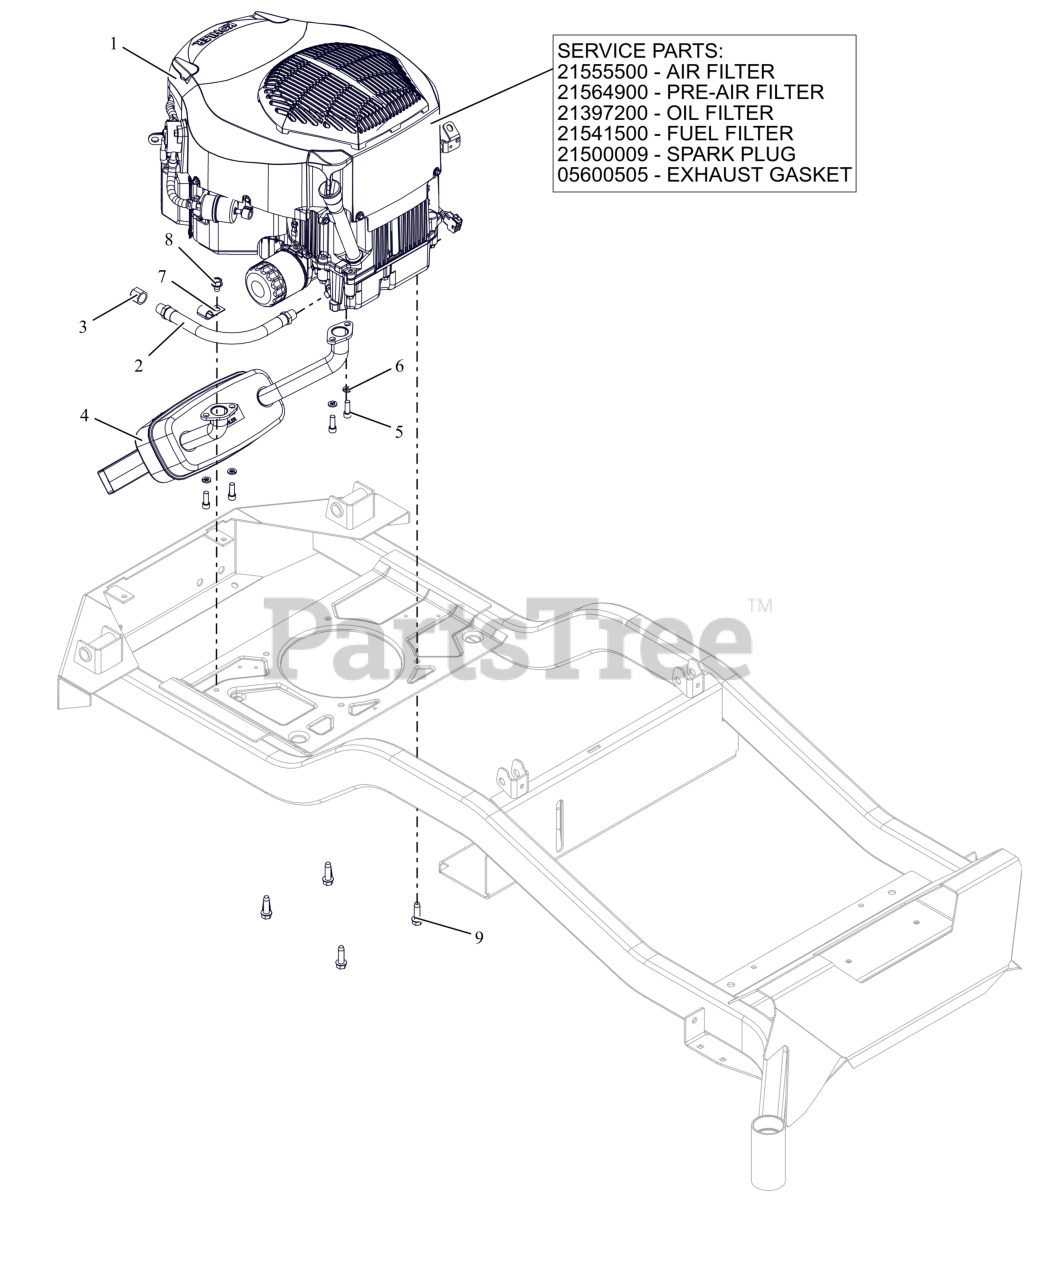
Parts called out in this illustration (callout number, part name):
1	ENGINE, KOHLER - KT730
1	AIR CLEANER, KOHLER
1	PRE-CLEANER, KOHLER
1	FILTER, OIL - KOH CV20
1	FILTER, FUEL
1	PLUG, SPARK KOHLER
1	GASKET, MUFFLER COURAGE TWIN
2	HOSE,HYD .38-11-0K M6NO-M6N0
3	PIPE CAP 3/8 NPT FEMALE
4	MUFFLER, KOHLER
5	SCR-CAP .31-18X.88 S/HD G8 ZCC
6	WSHR,LK-REG .312X.078 ZCC
7	J-CLAMP
8	SCR,TAP .375-16X.50 HWH TR ZCC
9	SCR,TAP .375-16X1.25HWH TR ZCC
